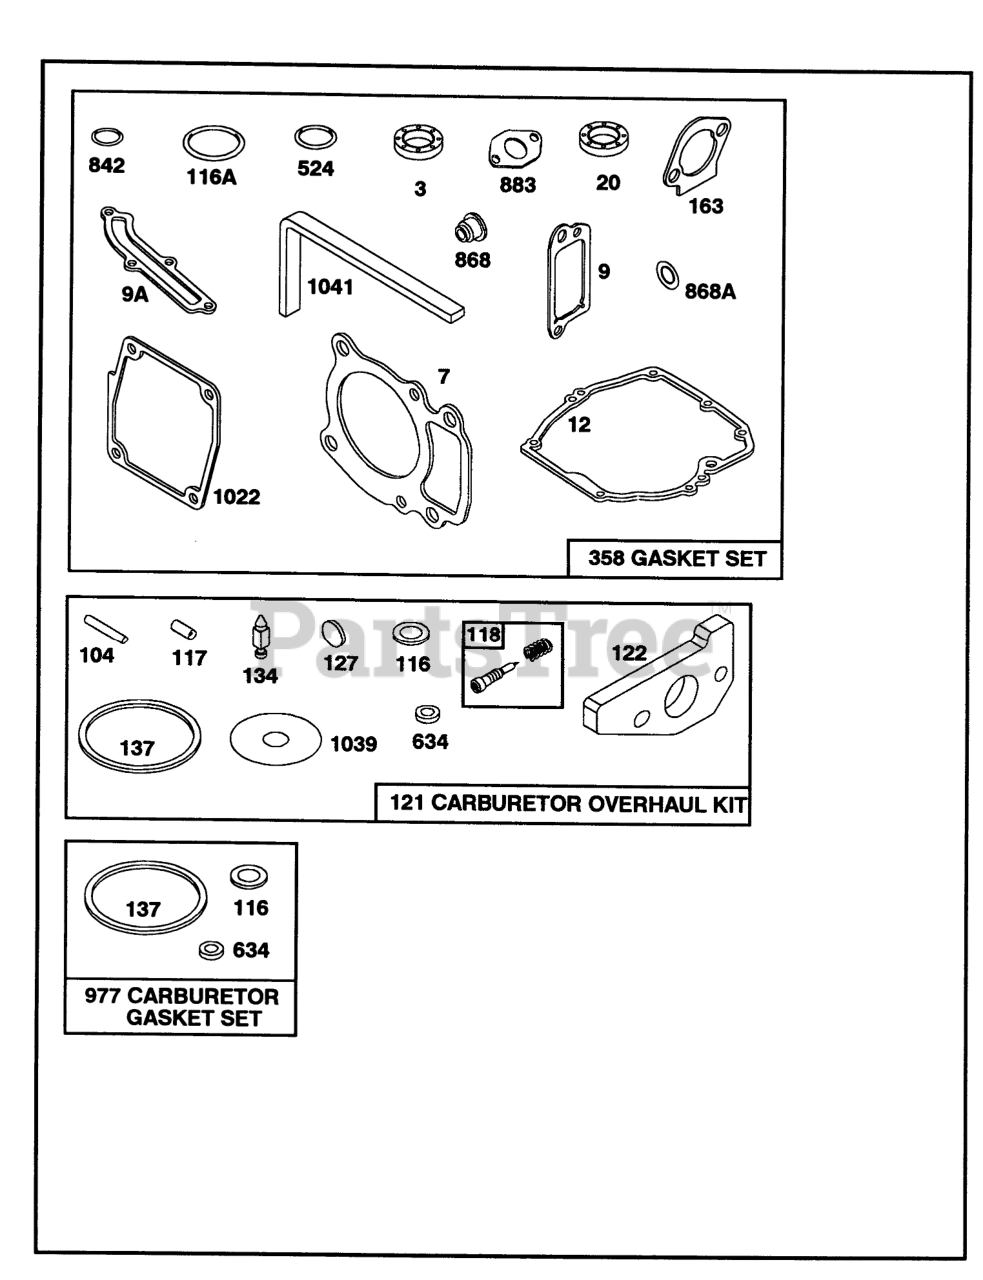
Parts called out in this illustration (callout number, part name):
3	SEAL - OIL
7	CYLINDER HEAD GASKET
9	Gasket-Breather
9A	GASKET-BREATHER
12	ENGINE BASE GASKET
20	SEAL-OIL
104	FLOAT HINGE PIN
116	SEALING GASKET
116A	O RING SEAL
118	VALVE KIT - NEEDLE
121	CARBURATOR OVERHAUL KIT
122	ADAPTER ASSEMBLY
134	Valve-Float (Includes Seat)
137	FLOAT BOWL GASKET
163	AIR CLEANER GASKET
358	GASKET SET
524	O-RING
634	SEAL WASHER
842	O-RING
868	SealAssy-Valve
868A	Seal-Valve
883	EXHAUST GASKET
977	CARBURATOR GASKET SET
1022	ROCKER COVER GASKET
1039	FLOAT LIMITER
1041	SEAL - FOAM
